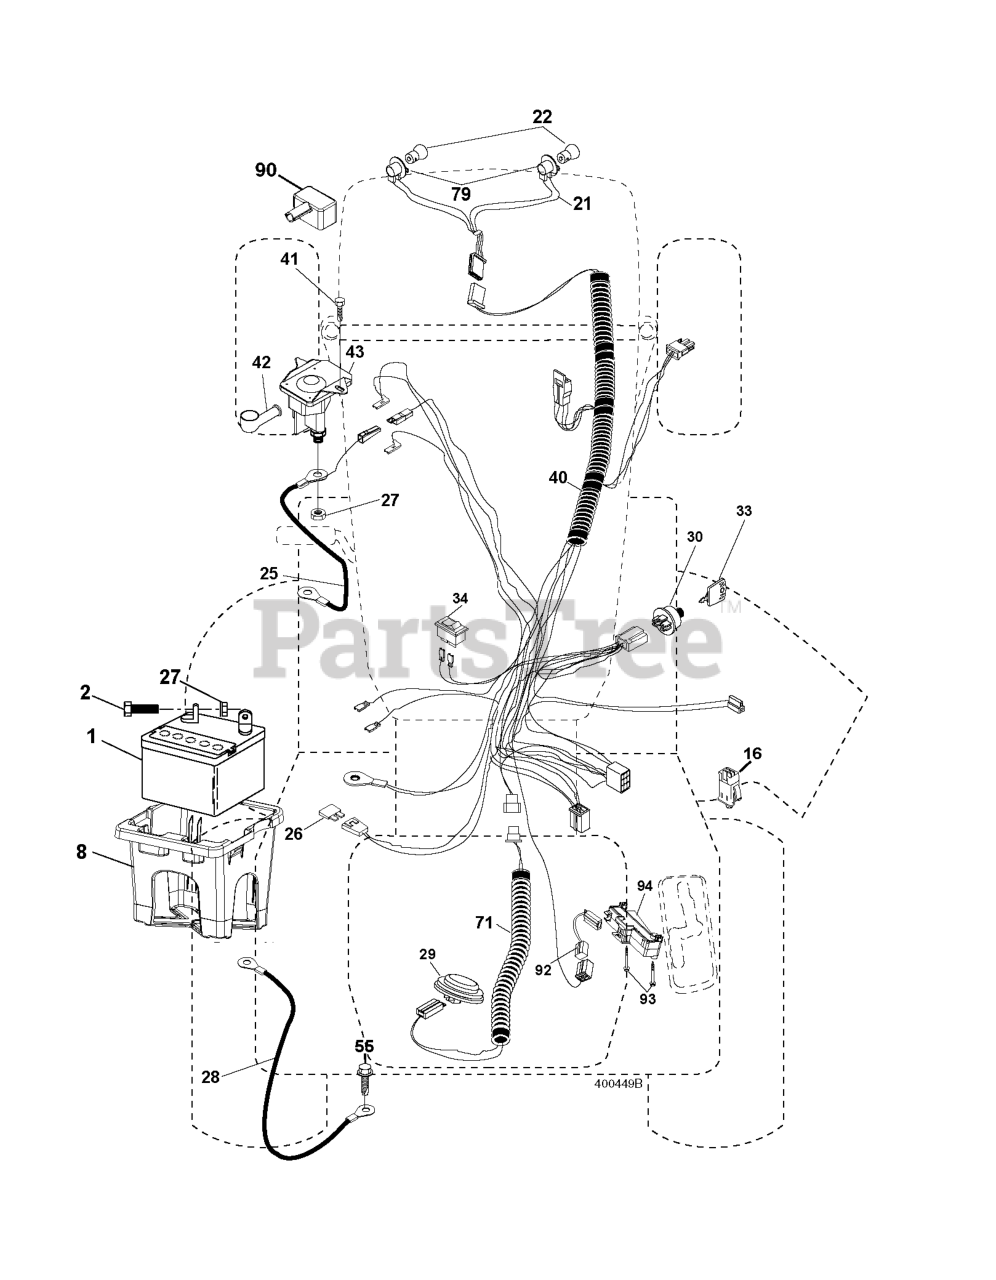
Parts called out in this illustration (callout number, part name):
1	BATTERY 12V .35 AMP
2	BOLT.HEX.1/4.X.3/4.DICHROMATE
8	BOX.BATTERY.MNT.REAR.L
16	SWITCH INTERLOOK PUSH-IN
21	HARNESS.LIGHT W/4152J BULBS
25	CABLE.STARTER.6GA.RED.
26	FUSE 20AMP
27	NUT
28	CABLE.BLACK.18"REAR.BA
29	SWITCH.SEAT.DELTA.OPC.
30	SWITCH.IGN.DELTA.W.LGH.ROS
33	KEY MLD GEN DELTA
40	HARNESS IGN. DASH
41	SCREW
42	TERMINAL COVER
43	SOLENOID.W/BRASS.PLUNGER
55	SCREW 5/16"
71	HARNESS.IGN.CHASS.TEX.REAR.BAT
79	BULB HOLDER ASM.
90	COVER, TERMINAL BATTERY
92	HARNESS.PIGTAIL.CONSLE
93	SCREW.PLASTITE
94	MODULE.REVERSE.ROS
